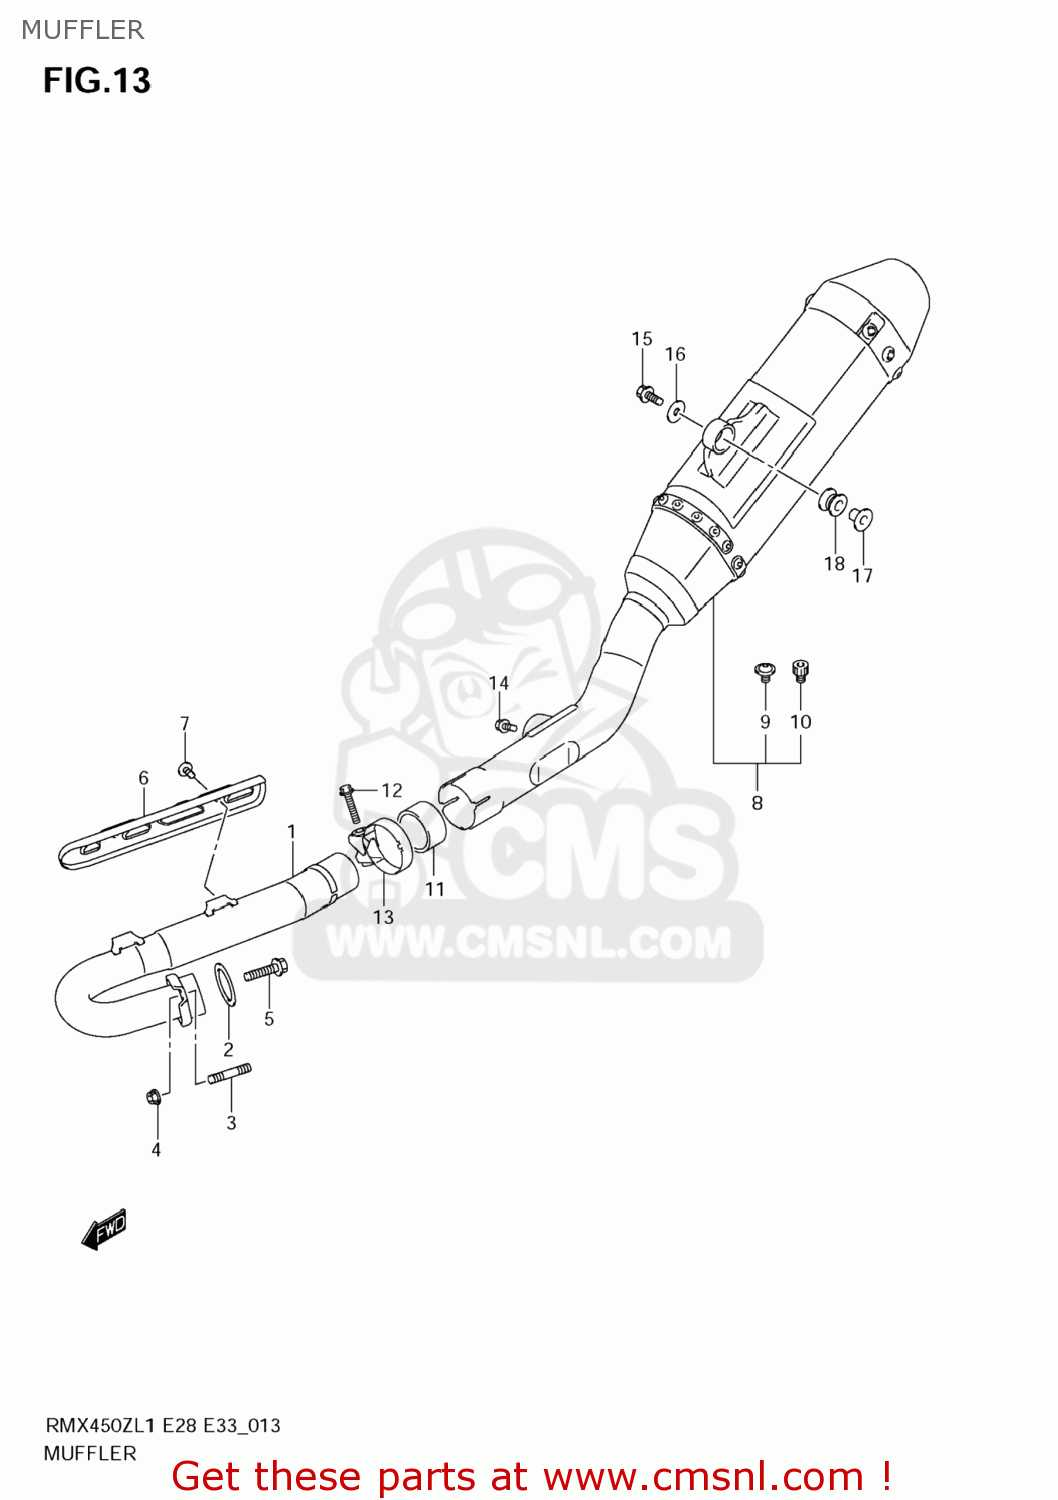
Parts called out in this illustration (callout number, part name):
1	PIPE,EXHAUST
2	GASKET,EXHAUST PIPE (NAS)
3	BOLT,STUD
4	NUT
5	BOLT(8X25)
6	COVER,EXHAUST PIPE
7	BOLT(6X8)
8	BODY,MUFFLER
9	SCREW(6X13)
10	BOLT
11	CONNECTOR,MUFFLER
12	BOLT(8X35)
13	CLAMP,CONNECTOR
14	BOLT(8X20)
15	BOLT(8X35)
16	WASHER(8.5X26X1.6)
17	SPACER(8.6X12X17.5)
18	CUSHION
